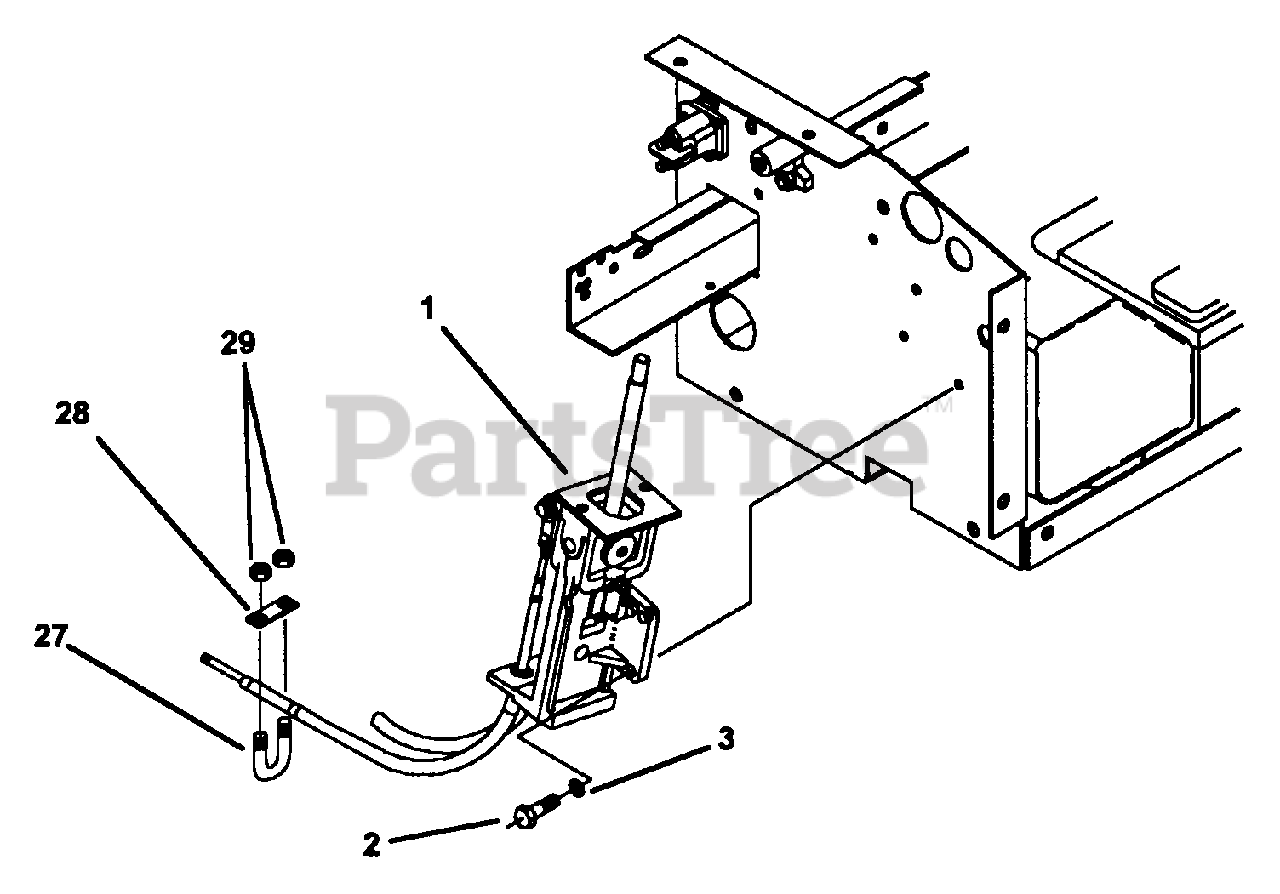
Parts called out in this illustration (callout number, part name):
1	JOYSTICK YOKE ASSEMBLY
2	CAP SCREW, 1/4-20 x 3/4", GR.5
3	LOCK WASHER, 1/4" SPLIT RING
27	U-BOLT, 5/16-18 X 1 3/16"
28	U-BOLT SPACER
29	NUT, 5/16-18, NYLOCK
